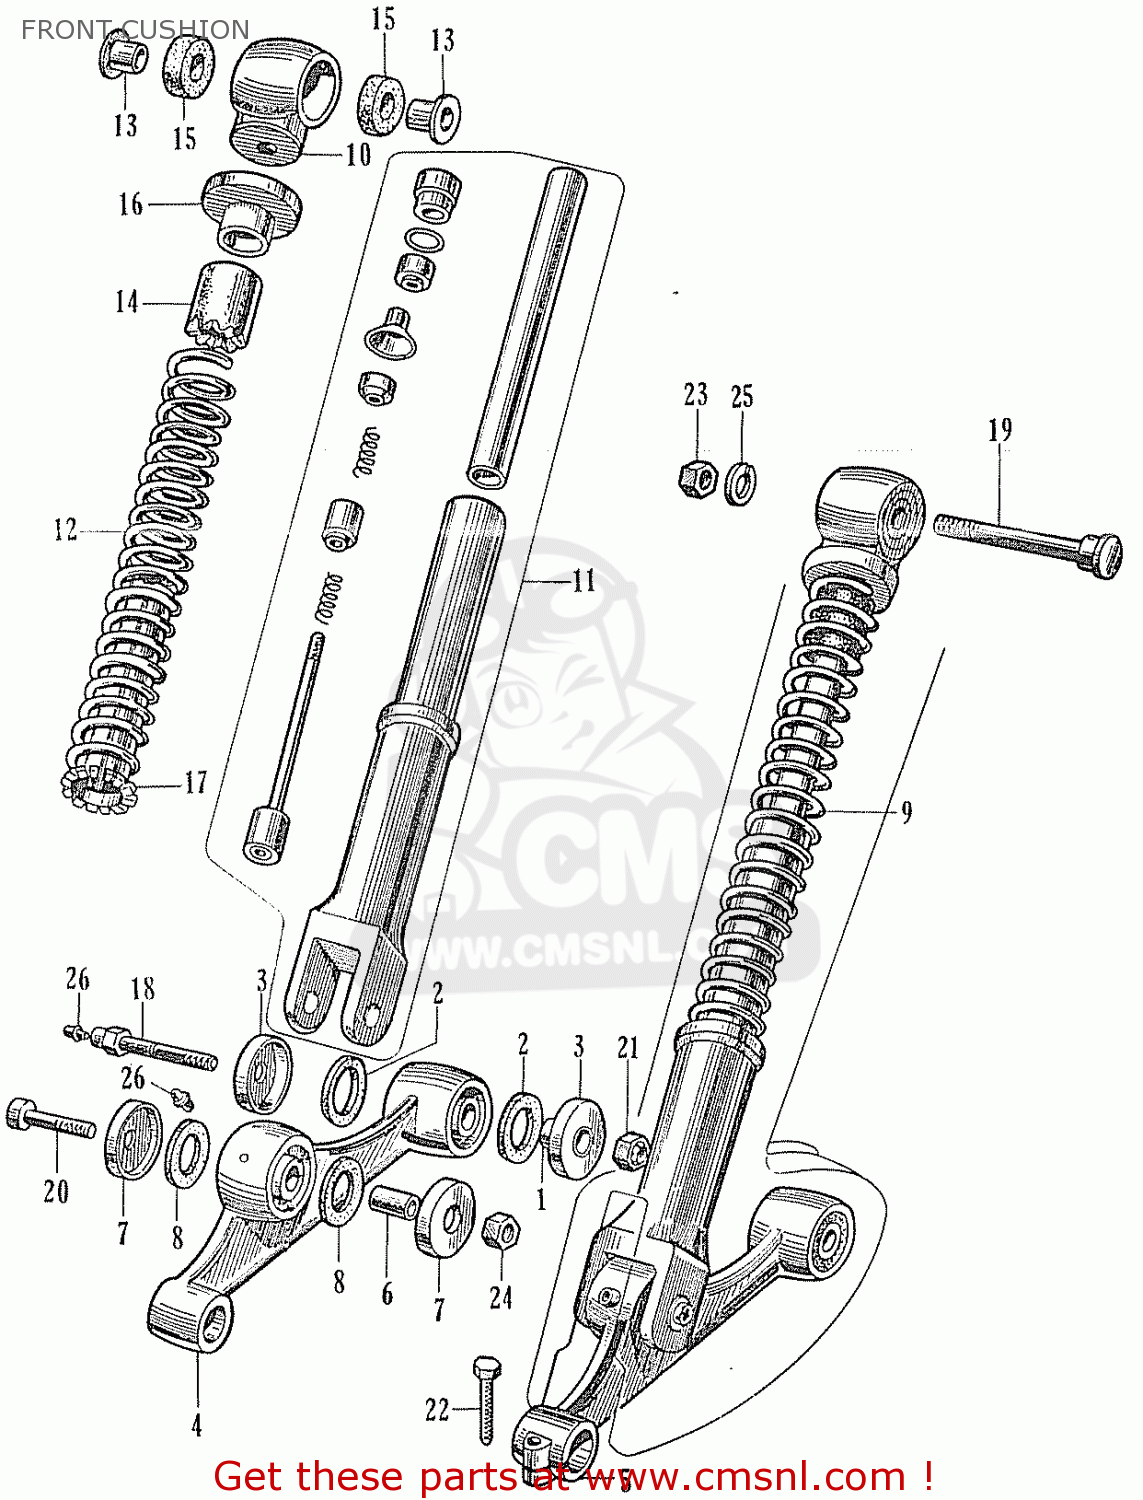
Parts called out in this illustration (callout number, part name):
1	COLLAR, ARM PIVOT
2	SEAL ARM
3	CAP, FRONT ARM
4	BUSH FRONT ARM
5	ARM L SUSPENSION
6	COLLAR CUSHION
7	CAP SEAL
8	DUST SEAL, FR. FORK
9	CUSHION ASSY
10	METAL CUSHION
11	METAL CUSHION
12	SPRING CUSHION
13	COLLAR CUSHION
14	RUBBER CUSHION
15	BUSH CUSHION
16	NUT, FRONT DAMPER
17	GUIDE,FR CUSHION
18	BOLT FRONT ARM
19	BOLT CUSHION
20	BOLT CUSHION
21	NUT LOCK 12MM
22	BOLT, HEX., 8X30
23	NUT.HEX 10MM
24	NUT, THIN, 10M/M
25	SPG-WASHER 10MM
26	NIPPLE,GREASE4.5
